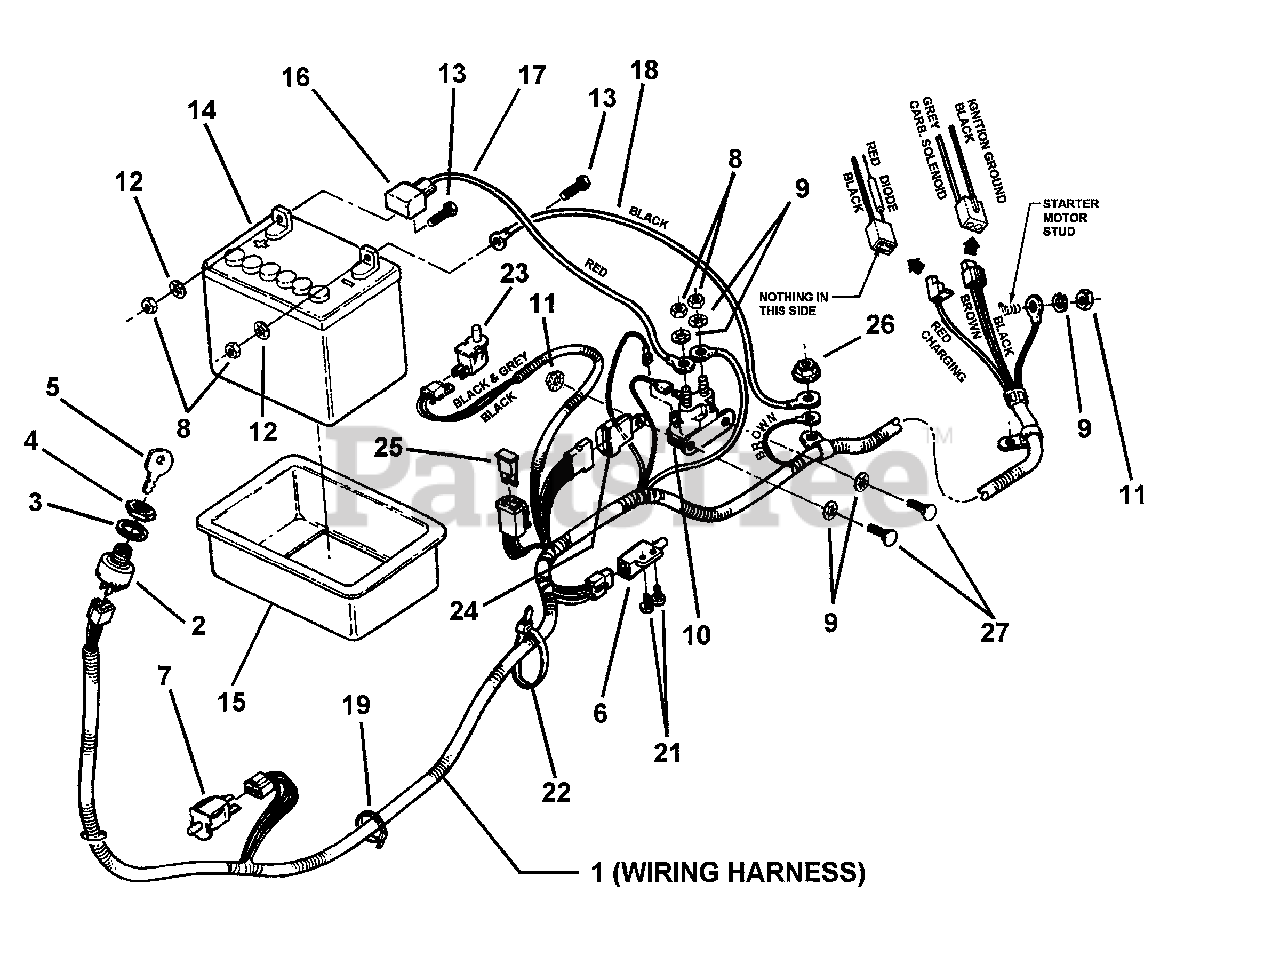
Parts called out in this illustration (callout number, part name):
1	WIRING HARNESS
2	SWITCH, Ignition
3	WASHER, 5/8" Int. Tooth Lock
4	NUT, 5/8-32 Hex (Special)
5	KEY, Switch
6	SWITCH, DPDT NC/NO
7	SWITCH, DP NO/NC Snap-In
8	NUT, 1 /4-20 Hex, Grade 5 or B
9	WASHER, 1 /4" Internal Tooth Lock
10	SOLENOID
11	NUT, 1 /4-20 Hex Flange Lock, Grade 5
12	RETAINER, 1 /4" Bolt
13	SCREW, 1 /4-20 x 5/8" Hex Head Cap, Grade 5
14	BATTERY, No-Spill, 7 Plate, 210 CCA, Dry Charge Type
15	TRAY, Battery
16	COVER, Battery Cable
17	CABLE, Positive (+ ), Red, 17"
18	CABLE, Negative (-), Black, 14"
19	CABLE TIE, 7" Long
21	SCREW, #10-24 x 1/2" Hex Washer Self-Tap (Torx)
22	WIRE TIE, Black Nylon, 11"
23	SWITCH, Seat, NC (Grey)
24	INTERLOCK, Module
25	FUSE, 20A
26	NUT, 5/16-24 Hex, Gr. 5
27	BOLT, 1 /4-20 x 3/4" Short Neck Carriage, Gr. 5
